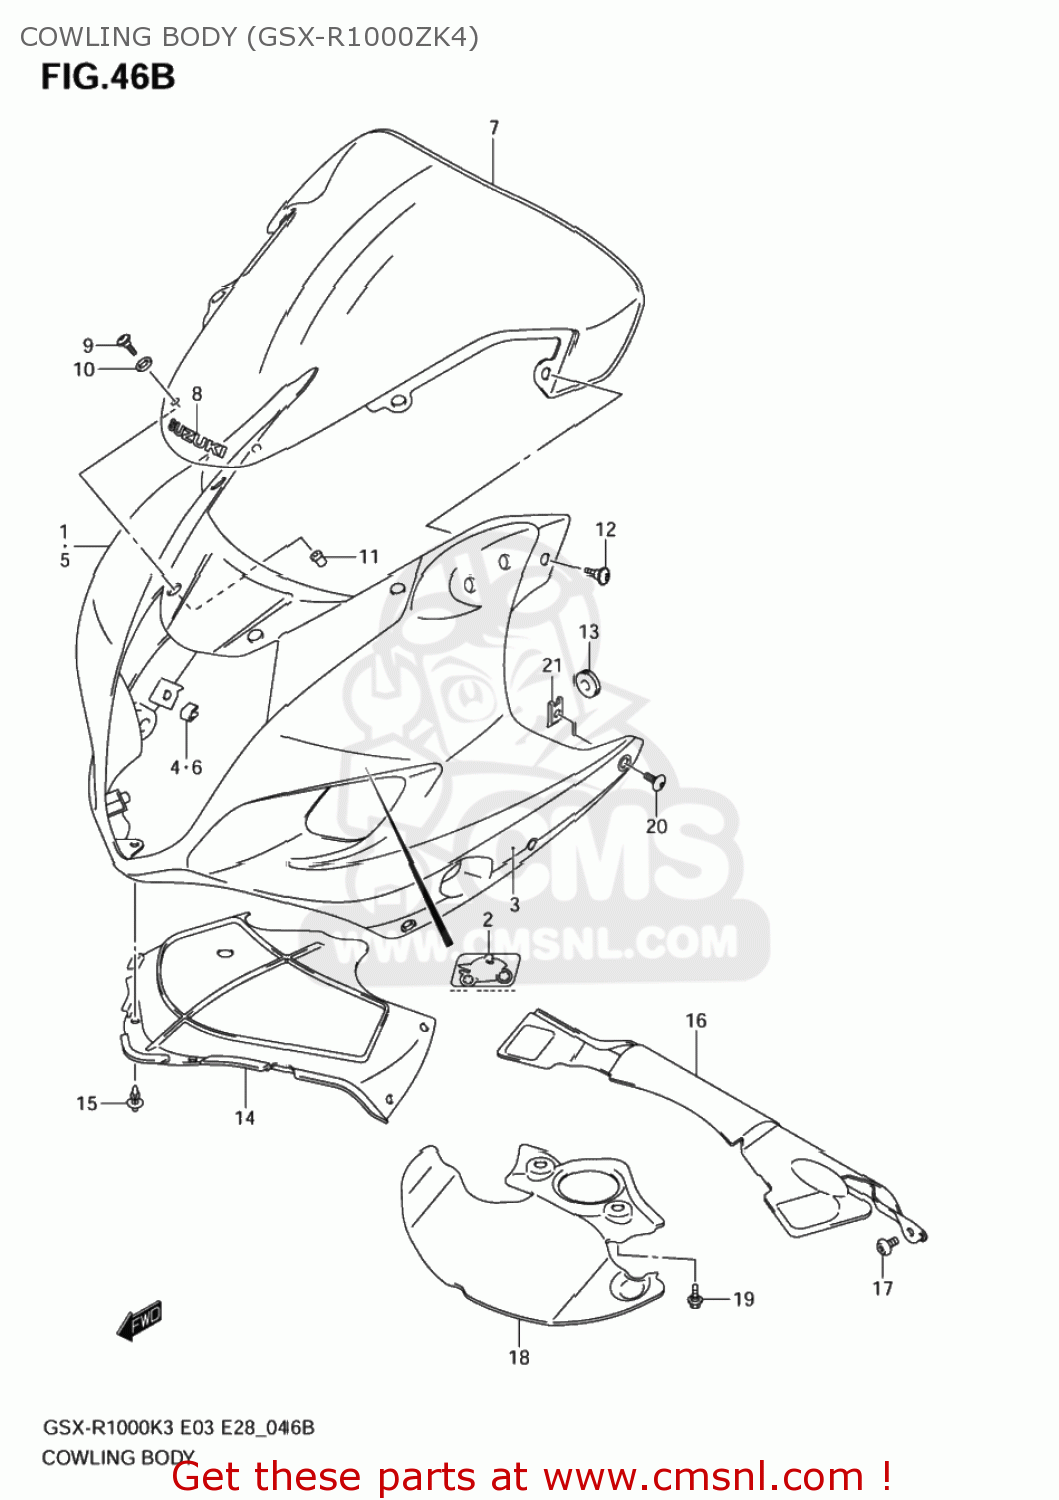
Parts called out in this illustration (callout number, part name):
1	COWLING,BODY(BLUE)
2	TAPE SET,BODY FR
3	TAPE SET,COWL BODY SIDE
4	CUSHION,FR LEG COVER
5	COWLING,BODY(BLACK)
6	CUSHION,FR LEG COVER
7	WINDSCREEN
8	TAPE,WINDSCREEN
9	SCREW(5X14)
10	WASHER
11	NUT
12	SCREW(5X16)
13	CUSHION
14	COVER,BODY COWLING
15	CLIP(BLACK)
16	COVER,COWLING FR LWR
17	BOLT(5X13)
18	COVER,LWR BRACKET
19	BOLT
20	SCREW(5X13)
21	NUT,COWL
